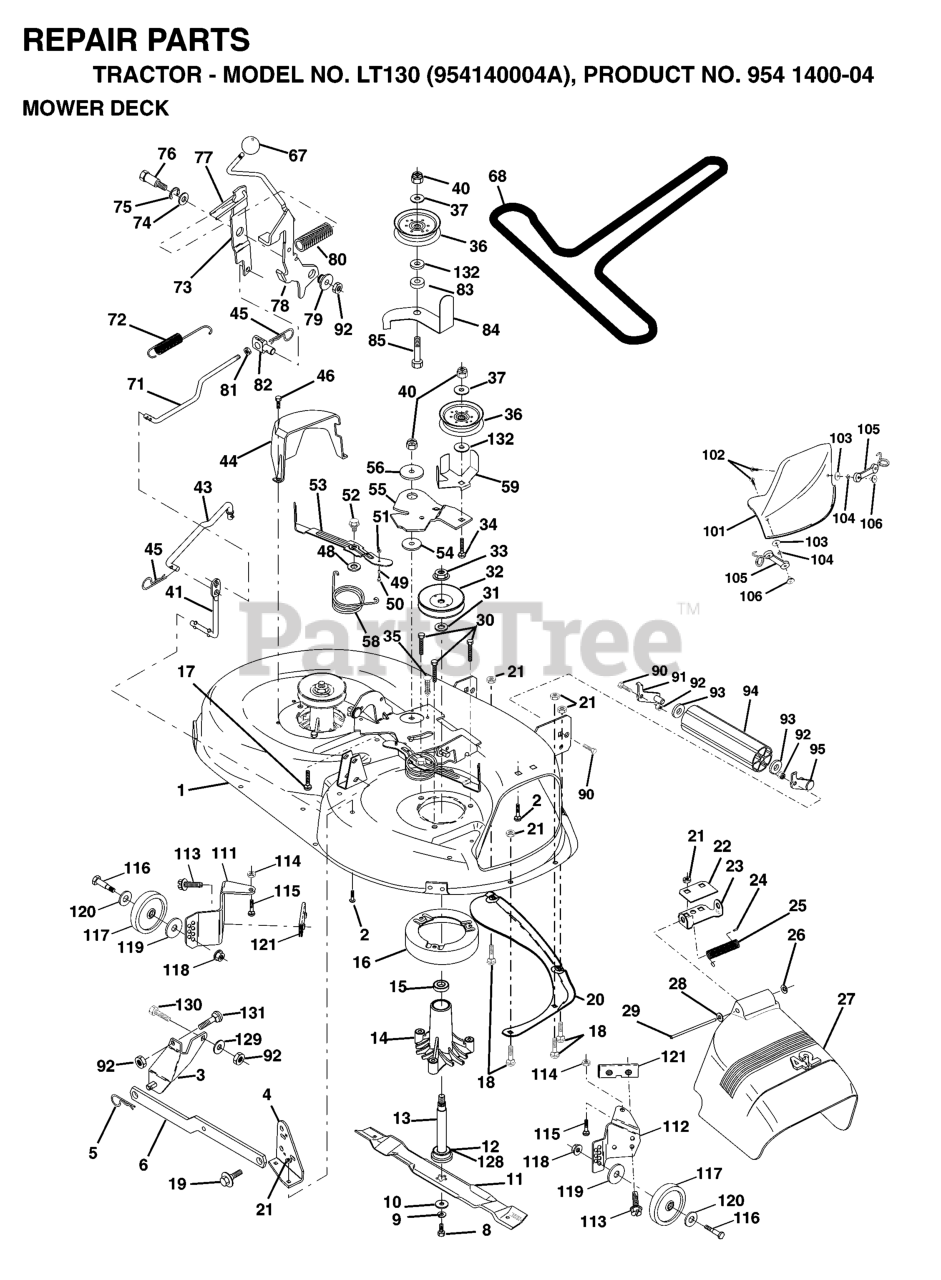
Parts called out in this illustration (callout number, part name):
1	DECK 42"
2	RP BOLT 5/16-18 X3/4 ZN/YEL GR
3	BRKT ASM SWAY BAR
4	BRKT DECK SW BAR
5	RETAINER-SPRNG RB
6	REAR SUSP ARM
8	BLADE BOLT
9	LOCKWASHER
10	WASHER.BLADE
11	BLADE.42".MULCH
12	BEARING.BALL.#6204.(MANDREL)
13	SHAFT ASM VENT
14	HOUSING.MANDREL.VENTED (MACHD)
16	STRIPPER
17	BOLT
18	BOLT
19	BOLT SHD 5/16-18
20	BAFFLE
21	LOCKNUT
22	STIFFENER BRACKET
23	DEFLECTOR BRACKET
24	CAP-SLEEVE LT
25	SPRING TORSION
26	NUT PUSH M
27	SHIELD.DEFLECTOR.MOWER.42".BLK
28	Washer 11/32 x 5/8 x 16 Ga SD
29	ROD.HINGE
30	SCREW
31	WASHER
32	PULLEY/MANDREL
33	NUT
35	FASTENER.XMAS.TREE
36	FLAT IDLER PULLEY
37	WASHER
43	CLUTCH ROD
44	GUARD MANDREL LH BLACK
45	RETAINER M
46	SCREW.1/4-20X5/8
49	ROLLER ASSY
52	BOLT.SHOULDER.5/16-18
53	ARM ASM PAD BRAD
54	HARDENED WASHER
55	ARM IDLER 42" MOWER LT/YT
56	SPACER RETAINER
59	GUARD, BELT
67	KNOB T (1/2-HOLE)
68	V-BELT TRIPATH
71	CLUTCH ROD
72	RETURN SPRING
73	ARM CLUTCH SECONDARY
77	KEEPER SPRING
78	ARM ASM CLUTCH PRIMARY
79	BUSHING.FLANGE.E-RING.GROOVE
80	SPRING-CLUTCH (2 2 PW01)
81	NUT
82	TRUNNION.ADJUSTABLE.3/8-16
84	KEEPER BELT
85	BOLT
90	BOLT
91	BRACKET LH (A)
92	NUT
93	Washer 1 17/32 X 7/8 X 16 Ga
94	NOSE ROLLER
95	BRACKET RH (B)
101	COVER MULCH 42"
102	SCREW
104	LOCKWASHER #10
105	LATCH ASSEMBLY
106	WELDNUT
111	BRACKET WHEEL GAUGE LH 42" DK
112	BRACKET WHEEL GAUGE RH 42" DK
113	SCREW.THDROL.5/16-18X3/4.TTY
114	NUT
115	BOLT.CARR.5/16-18X1/2
116	BOLT M
117	WHEEL.GAUGE.BLK.4.93
118	LOCKNUT
119	WASHER.5/16.FLAT.STE.STD.
120	Washer 17/32 x 15/16 x 12 Gauge
121	BRACKET.EXTRUDED.GAGE.WHEEL
128	WASHER FELT
129	WASHER
131	BOLT D
